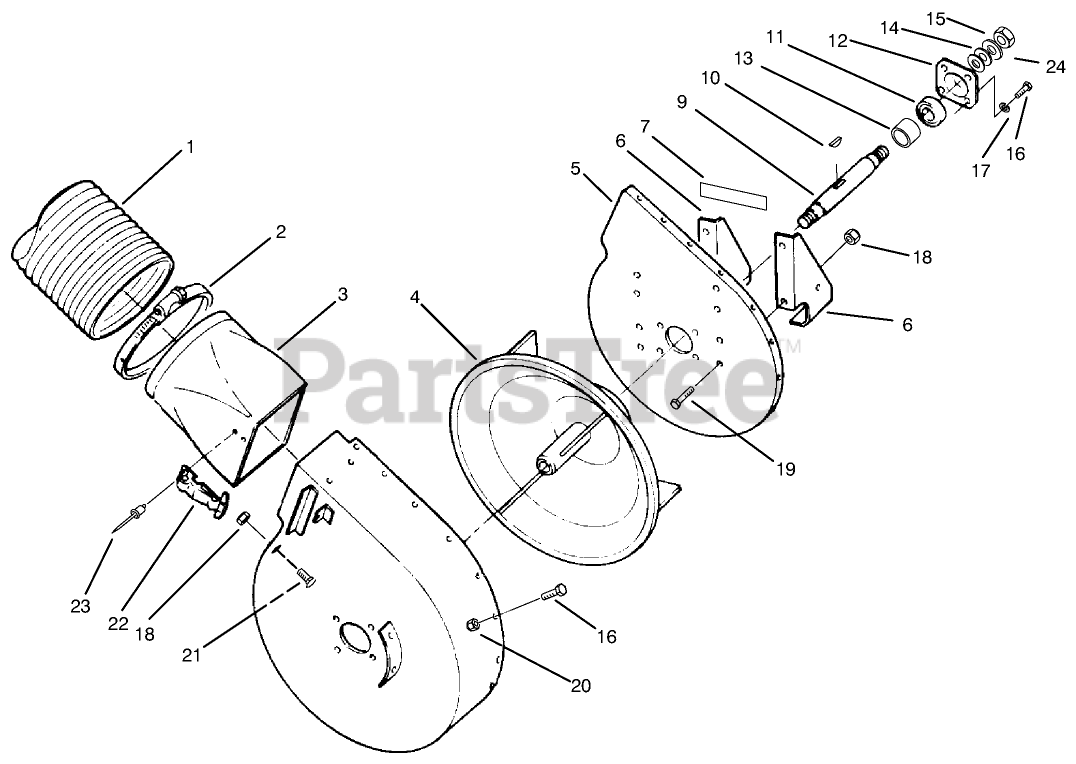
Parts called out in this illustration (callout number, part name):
1	Hose-Flexible (Ref.)
2	CLAMP
3	ADAPTER
4	IMPELLER - WELDED BLACK
5	Plate-Mount
6	BRACKET-BLOWER MT B
7	DECAL
8	SPACER-BEARING
9	SHAFT- BLOWER
11	BEARING-BALL
12	CUP-BEARING
13	SPACER
14	WASHER-FLAT
15	NUT 5/8-11 L.H.
16	SCREW-HH
17	WASHER-LOCK
18	NUT-LOCK, NI
19	SCREW-HH
20	NUT-LOCK, NI
21	BOLT-CARR
22	HANDLE ASM
23	RIVET-POP
24	WASHER-FLAT
